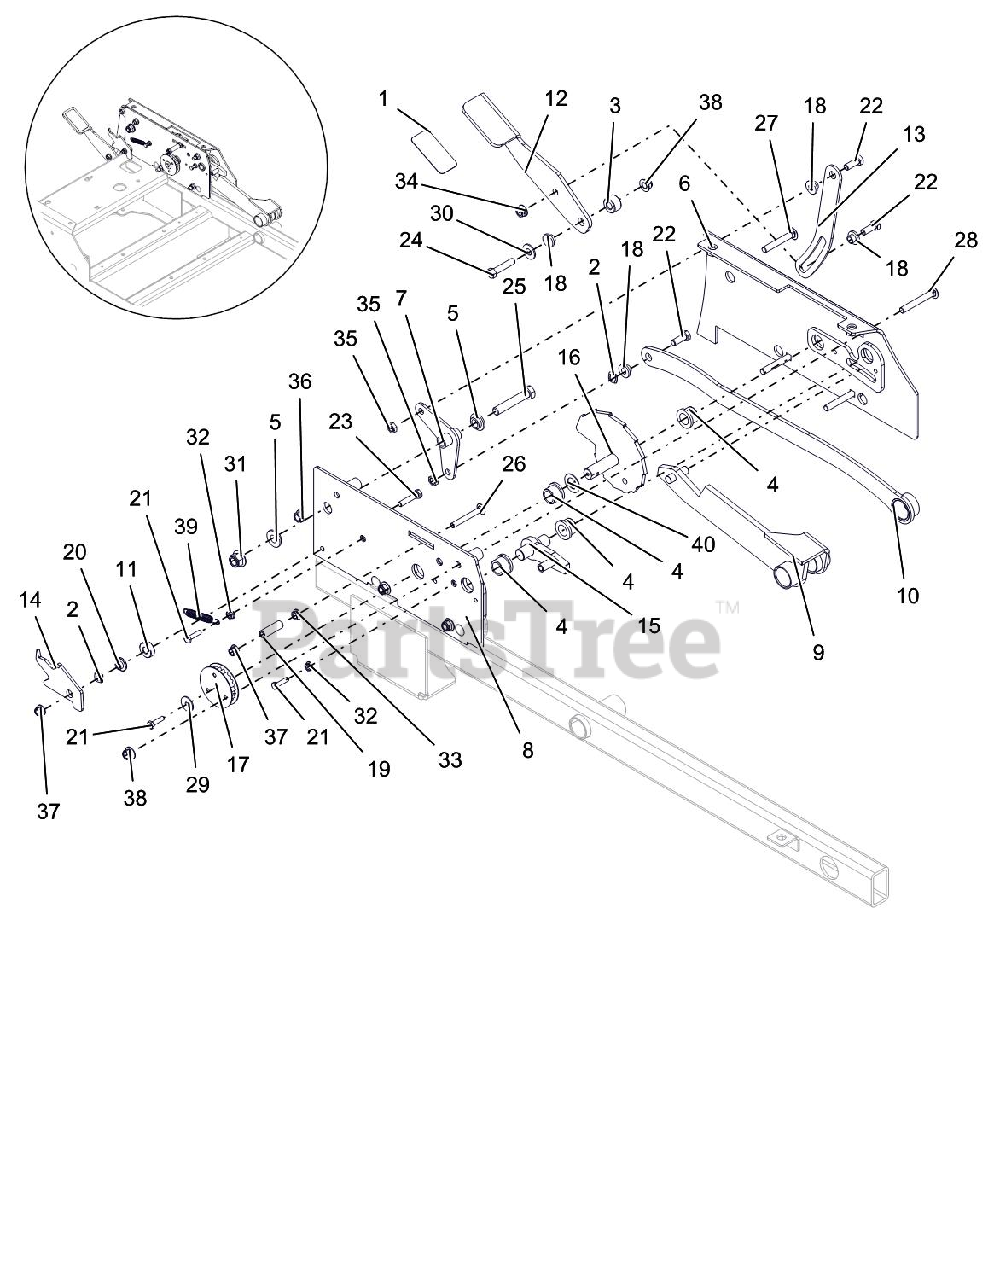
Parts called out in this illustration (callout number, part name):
1	GRIP, PEDAL 1.50 X 3.00
2	WAVE WASHER .531X.781X.125FH
3	SPACER, .437X1.00X.58 SMLS
4	BUSHING, FLANGE .75X.75X1.0
5	BSHG-FLG .515X.750X.310X1.120
6	SIDE, LH BOTTOM TOWER
7	WLDMT, REAR PIVOT
8	WLDMT, CAM COVER
9	WLDMT, CAM CONTACT
10	WLDMT, DECK LIFT LINK
11	SPCR, .375 X 1.00 X .342
12	PEDAL, DECK LIFT
13	LINK, DECK LIFT PEDAL
14	LATCH, FOOT PEDAL
15	WLDMT, DECK LOCK
16	WLDMT, HEIGHT OF CUT
17	WLDMT, LOWER PULLEY
18	BSHG-FLG .385X.500X.875X.406
19	BSHG-SLV .325X.49X1.56
20	BSHG-FLG .32X.500X.344X.880
21	@BLT-HEX .25-20X1.00 GR5 YWZC
22	@BLT-HEX .38-16X1.00 GR5 YWZC
23	@BLT-HEX .31-18X1.50 GR5 YWZC
24	@BLT-HEX .38-16X1.75 GR5 YWZC
25	@BLT-HEX .50-13X2.75 GR5 YWZC
26	@BLT-RDHDSQNK .31-18X2.50 G5YZ
27	@BLT-RDHDSQNK .38-16X2.50 G5YZ
28	@BLT-RDHDSQNK .38-16X2.75 G5YZ
29	WSHR-FL-STL .281X1.000X.063
30	@WSHR-FL-STL.438X1.00X.083 YWZ
31	@NUT-LK-NYL-FLG .50-13 YWZC
32	@NUT-SPNLK-FLG .25-20 YWZC
33	@NUT-SPNLK-FLG .312-18 YWZC
34	NUT-LK-CTR-FLG .38-16 YWZC
35	@NUT-LK-CTR-JAM .375-16 YWZC
36	@NUT-LK-TOP-FLG .38-16 YWZC
37	@NUT-LK-NYL-FLG .31-18 YWZC
38	@NUT-LK-NYL-FLG .38-16 YWZC
39	SPRING, EXTENSION
40	WSHR-FL-STL .750X1.250X.048 YZ
